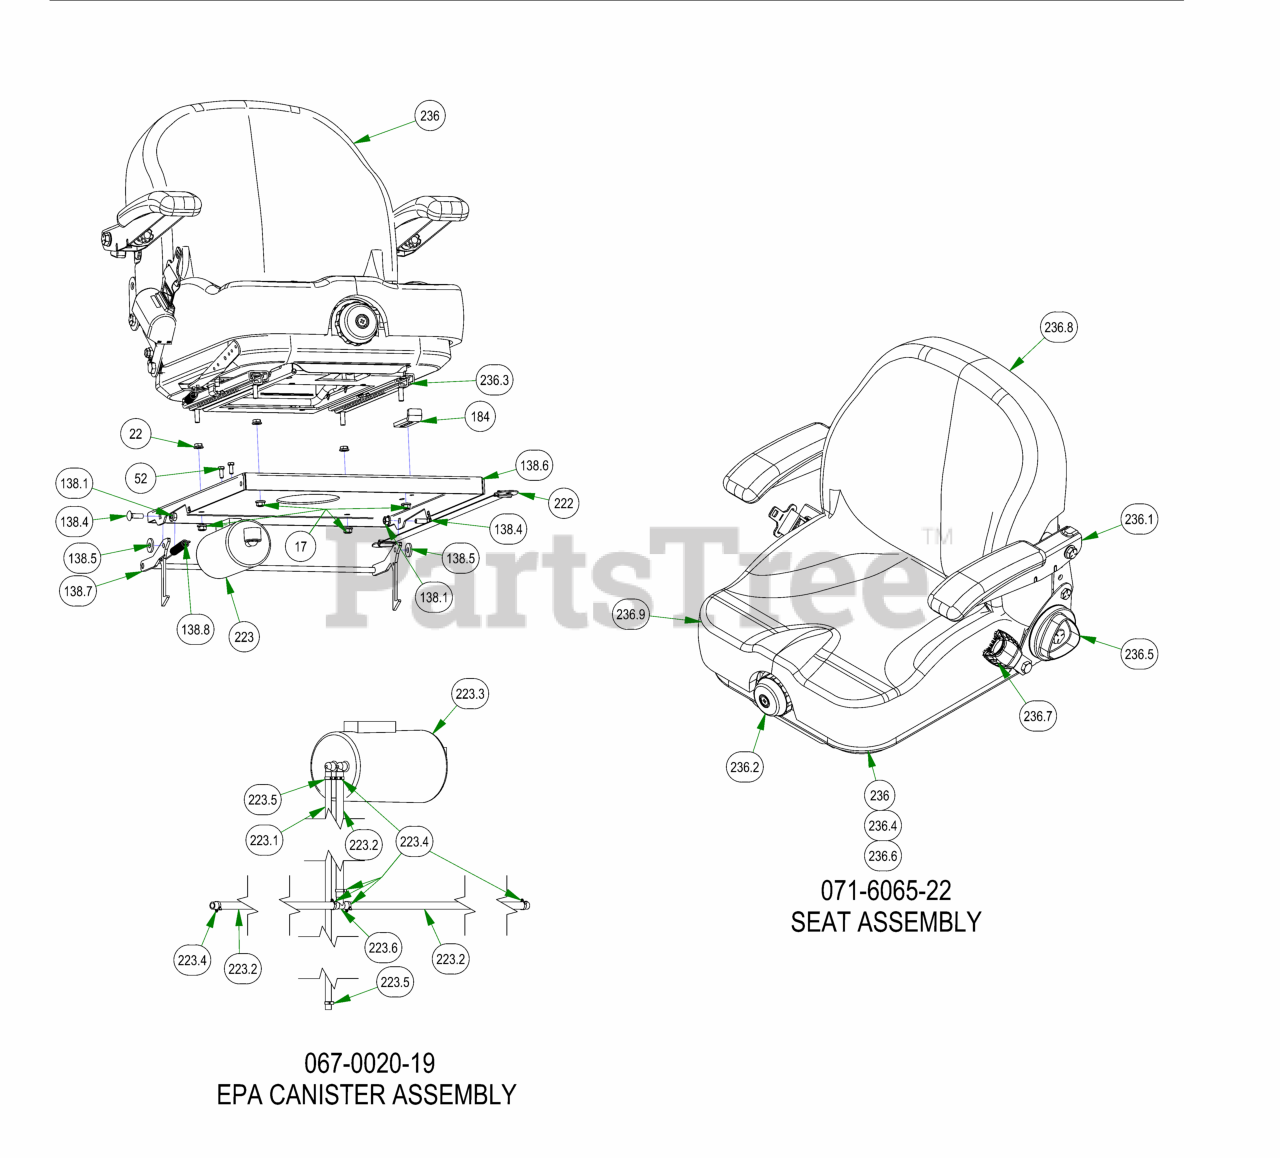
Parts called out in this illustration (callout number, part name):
17	5/16-18 NYLON INSERT FLANGE LOCKNUT ZINC
22	5/16-18 HEX SERRATED FLANGE NUT HARD/ZINC
52	M6-1.0 X 16MM DIN 933 HEX TAP BOLT (CL 8.8) ZINC
138.1	5/16-18 NYLON INSERT FLANGE LOCKNUT ZINC
138.4	5/16-18 X 1 CARRIAGE BOLT (GR.8) ZINC
138.5	.360 ID X .983 OD X .120 THICK FLAT WASHER NYLON
138.6	R-SERIES SEAT PLATE
138.7	Seat Latch Rod Assembly
138.8	Brake Spring
184	Seat Stop
222	Seat Strap with Buckles
223	2019 Outlaw EPA Cannister Assembly
223.1	3/16" Vinyl Tubing, 66" Long
223.2	1/4" Vinyl Tubing 38" Long
223.3	Carbon Canister
223.4	3/16 Vinyl Clamp
223.5	3/16" Vinyl Hose Clamp
223.6	fuel line T
236	2022 Suspension Seat w/Seatbelt
236.1	Set of Armrests-SS Front Adj
236.2	Weight Adjust Indicator Knob Assy
236.3	4" Single Locking Track Kit
236.4	Delta Plunger Switch - N.O.
236.5	Recliner Adjustment Knob-New
236.6	Bellows w/Hardware
236.7	2" Retractable Belt Kit w/Spacers
236.8	Back Cover for I3M - Recl - Logos
236.9	Cushion Cover Kit for I3M-Logo
